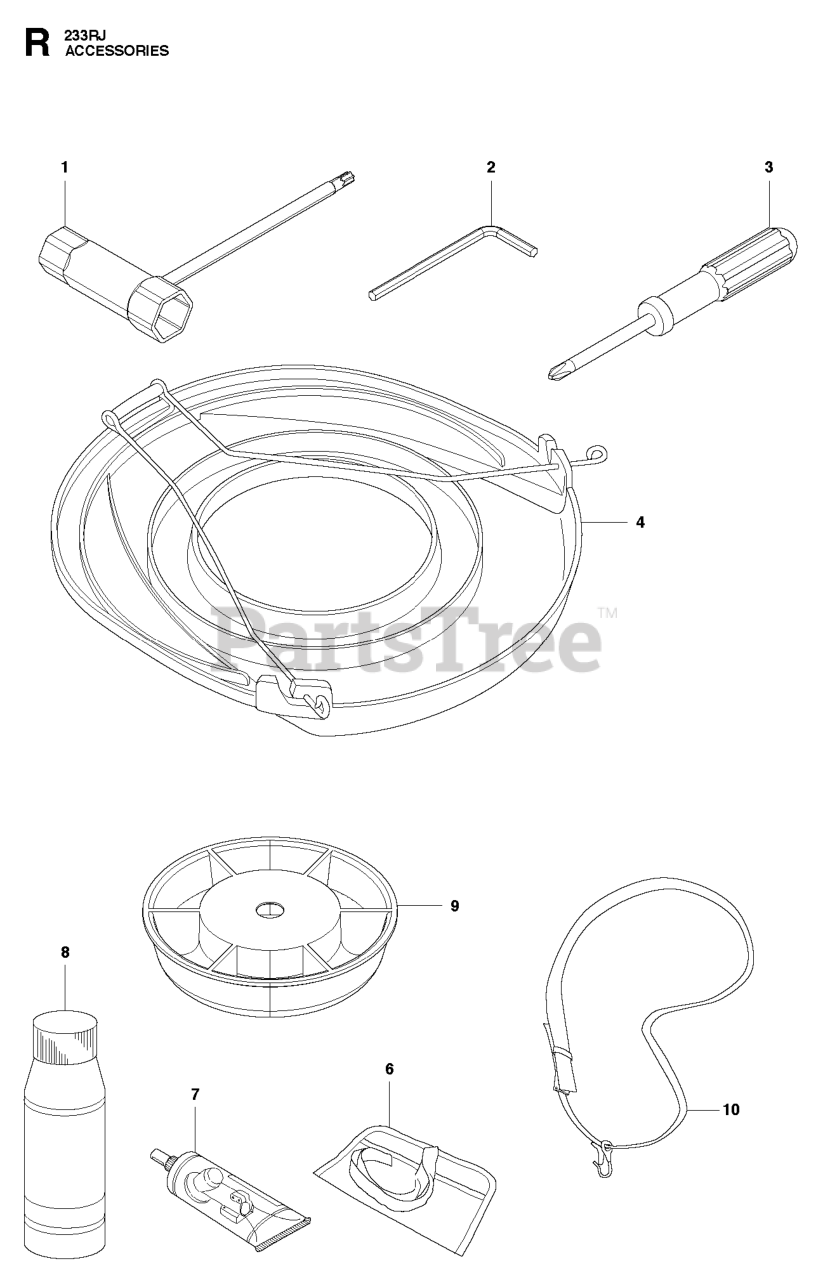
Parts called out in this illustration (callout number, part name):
2	BAR
3	SCREWDRIVER
4	BLADE GUARD TRANSPORT
5	Harness-w/o warning
7	BEVEL GEAR GREASE
8	Air Filter Oil 1l.
9	SUPPORTING CUP
10	Harness-w/o warning
